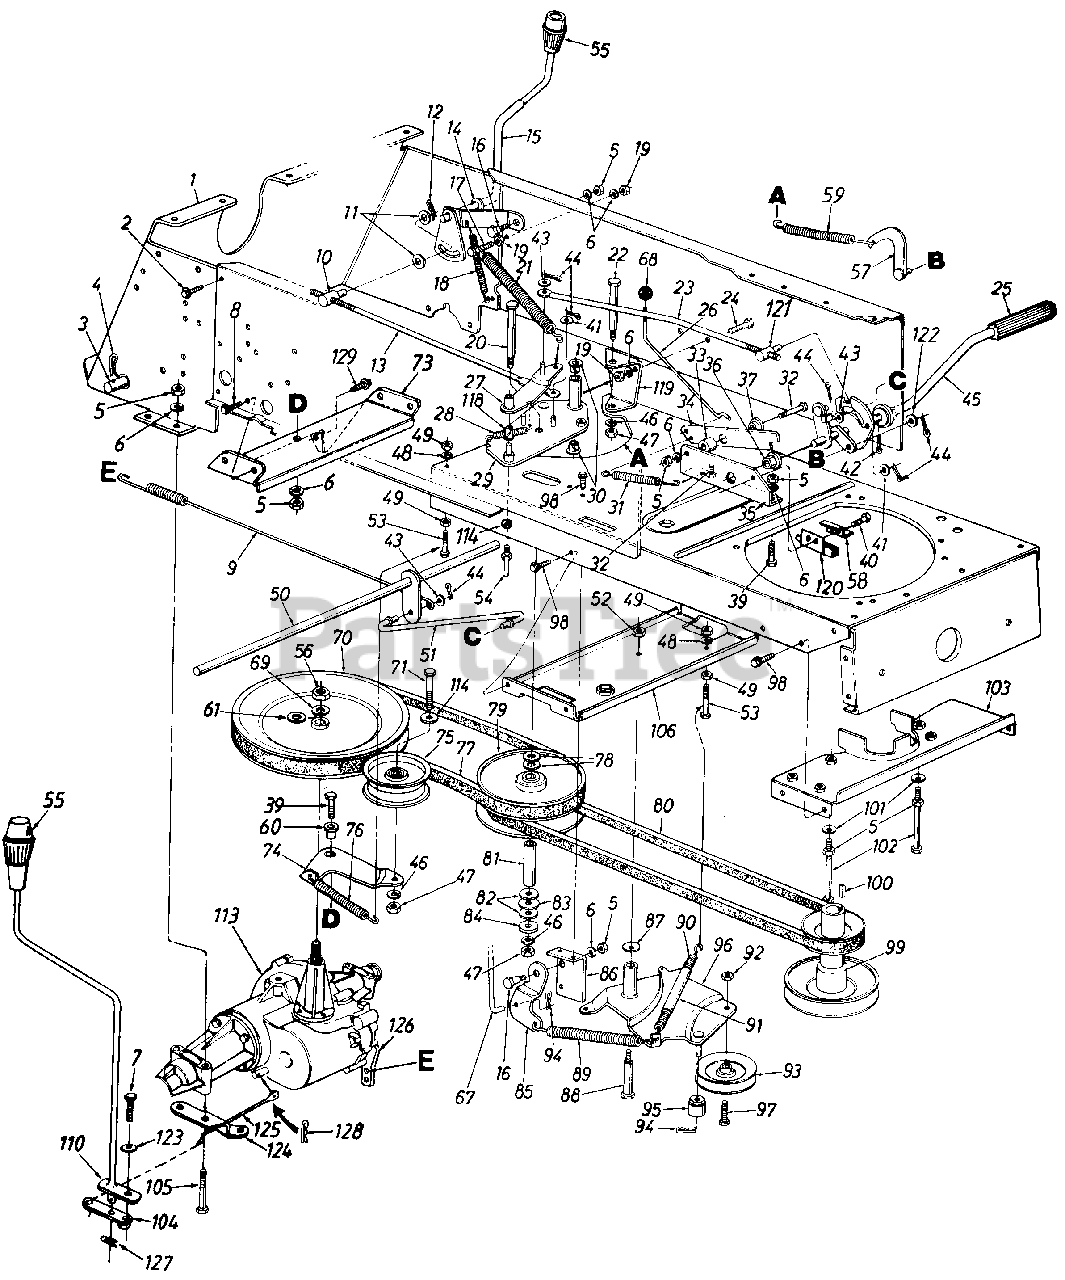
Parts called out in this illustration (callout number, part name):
1	Hitch Plate
2	Hex AB-Tap Scr. 5/16" x .75"
3	Hitch Rod
4	Hitch Pin Clip
5	Hex Nut 5/16-18 Thd.
6	L-Wash. 5/16" I.D.
7	Hex Bolt 1/4-28 x .62" Lg.
8	Hex Wash. Hd. TT-Tap Scr. 5/16-18 x .62" Lg.
9	Brake Extension Spring
10	Adjustment Ferrule 3/8-24 Thd.
11	Fl-Wash. .385" I.D. x .87"
13	Speed Control Link (Rear)
14	Fl-Wash. .531" I.D. x.94"
15	Speed Selector Lever Ass'y.
16	Shld. Bolt .437" Dia. x .162"
17	Hex Bolt 5/16-24 x 1.25" Lg.
18	Extension Spring 3.9" Lg.
19	Hex Nut 5/16-24 Thd. (Gr. 5)
20	Hex Bolt 3/8-24 x 4.5" Lg.
21	Extension Spring 11" Lg.
22	Shld. Bolt .625" Dia. x 3.5" Lg.
23	Speed Control Link (Front)
24	Hex Bolt 5/16-24 x .75" Lg.
25	Foot Pad
26	Parking Brake Link
29	Pulley Plate Ass'y.
30	Flanged Brg. .630" I.D.
31	Extension Spring 2.51" Lg.
32	Hex Bolt 5/16-18 x 1.25" Lg.
33	Spacer .34" I.D. x .88"
36	Hex Flange Brg. .634" I.D.
37	Shld. Spacer .5" Dia.
39	Hex Bolt 5/16-18 x .75" Lg.
40	Hex B-Tap Scr. #10 x 5/8 Lg.
41	Fl-Wash. .406" I.D. x .75" O.D.
42	Cotter Pin 1/8" Dia.
43	Fl-Wash. .34" I.D. x .68" O.D.
44	Cotter Pin 3/32" Dia.
47	Hex Nut 3/8-24 Thd.
48	L-Wash. 1/4" I.D.
49	Hex Nut 1/4-20 Thd.
50	Brake Link Bracket
51	Front Brake Rod Link
52	Hex Cent. L-Nut 3/8-16 Thd.
53	Hex Bolt 1/4-20 x 2.0" Lg.
54	Belt Guard Pin
55	Shift Knob
56	Hex Jam Nut 9/16-18 Thd.
57	Foot Pedal Brkt. Ass'y.
58	Switch Plate
59	Ext. Spring 5.2" Lg.
60	Shld. Spacer .318" I.D. x 1.125"
61	Fl-Wash, .635" I.D. x 1.12" O.D.
67	Deck Control Rod
68	Ball Knob Brake
69	Belt-Wash. 9/16" I.D. x 1.25"
70	V-Pulley 9 1/4" O.D.
71	Hex Bolt 3/8-24 x 1.75" Lg.
75	Flat Idler 3.5" O.D.
76	Extension Spring 6.12" Lg.
77	V-Belt
78	Teflon Washer 1.20" O.D.
79	Variable Speed Pulley 6" Dia.
80	V-Belt
81	Pivot Bushing
82	Fl-Wash. .56" I.D. x 1.0" O.D.
83	Thrust Brg. .56" I.D. x 1.25"
84	Retainer Cup
85	Deck Control Pivot Brkt.
86	Parking Brake Mtg. Brkt.
87	Bell-Wash. .38" I.D. x .88" O.D.
88	Shld. Bolt .498" Dia. x 2.05"
89	Extension Spring 6.12" Lg.
90	Extension Spring 6.37" Lg.
91	Convoluted Conduit 4" Lg.
92	Hex Cent. L-Nut 3/8-24 Thd.
93	V-Belt Idler
94	Internal Cotter Pin
95	Spacer
96	Idler Brkt. Deck Ass'y.
97	Hex Bolt 3/8-24 x 1.5" Lg.
98	Hex TT-Tap Scr. 1/4-20 x .5"
99	Engine Pulley
100	Sq. Key 1/4 x 1.5" Lg.
101	Bell-Wash. .345" I.D. x .88"
102	Hex Bolt 5/16-18 x 5.25" Lg.
103	Belt Keeper Brkt. Ass'y.
104	Shift Lever Link Ass'y.
105	Hex Bolt 5/16-18 x 3.25" Lg.
106	Deck Idler Support Brkt.
110	Shift Lever Ass'y.
113	Transmission Comp.
114	Fl-Wash. 3/8" I.D. x 1.0" O.D.
118	Nyliner Flanged Brg.
119	Variable Speed Support Brkt.
120	Safety Switch (Clutch)
121	Adjustment Ferrule 3/8-24 Thd.
122	Fl-Wash. .344" I.D. x .62" O.D.
123	Bell-Wash. .265" I.D. x .75" O.D.
124	Shift Lever Support Brkt.
125	Shift Lever Rod
126	Actuating Arm
127	Cotter Pin 3/4" Lg.
128	Internal Cotter Pin
129	Hex Wash. Hd. TT-Tap Scr. 5/16-18 x 1.75" Lg.
